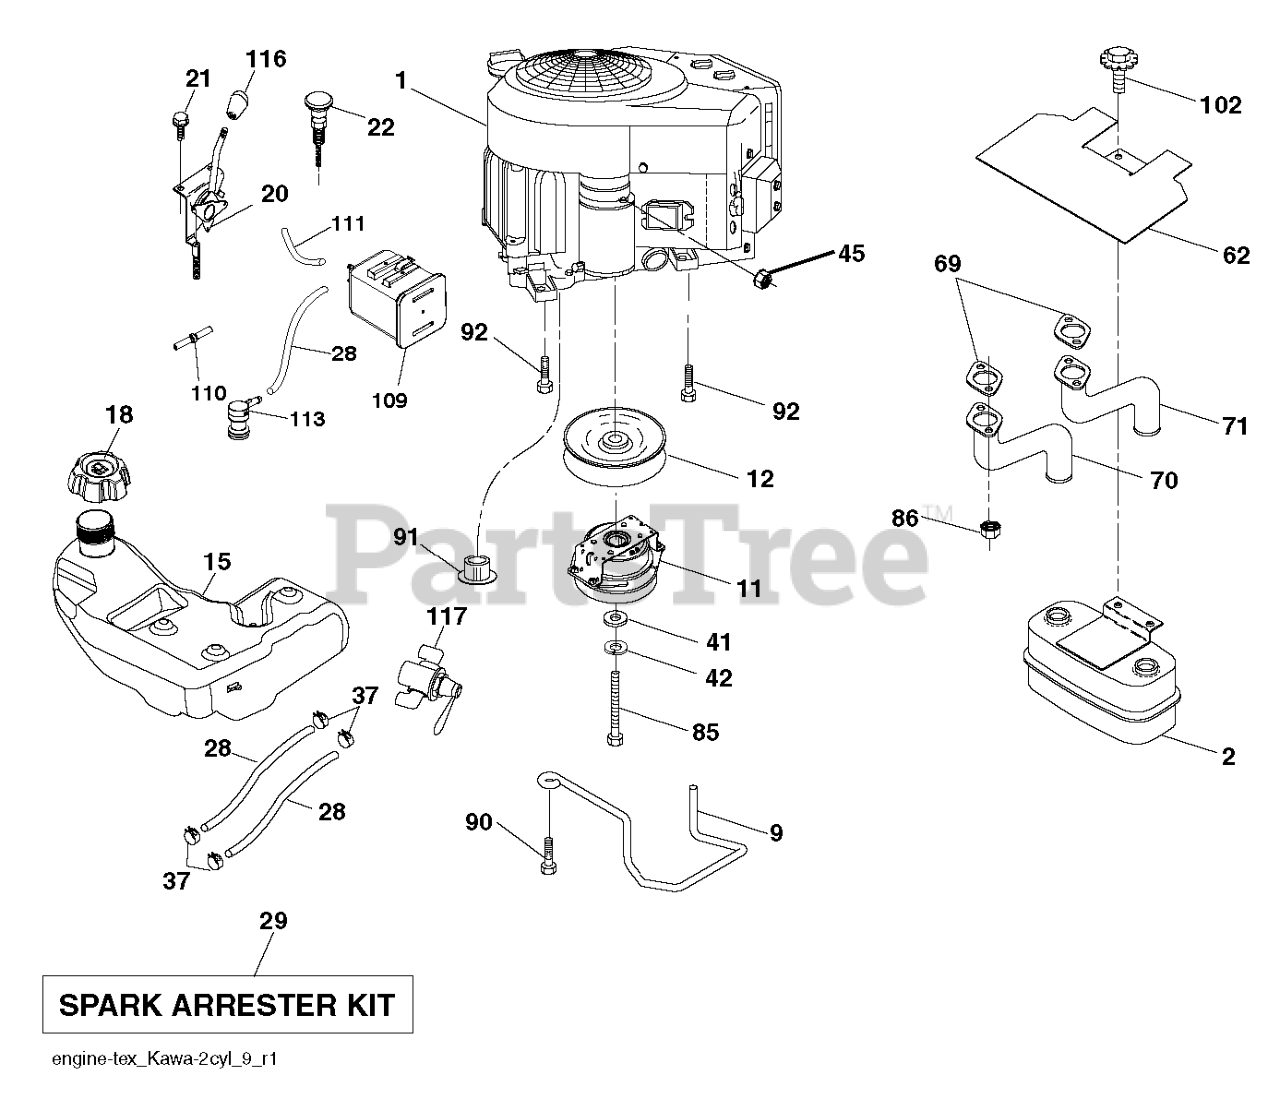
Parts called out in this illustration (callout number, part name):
2	MUFFLER.ASM.TWN.EXTNDED.DFLCTR
9	KEEPER BELT ENGINE
11	CLUTCH MZ ZTR GT.48/54"1.125"
12	PULLEY ENGINE
15	RP_TANK.ASM.4.GAL.CARB.2.PORT
18	CAP.FL.R.3'N/CARB.H.CROWN.498
20	CONTROL.THROTTLE.PRO.
21	SCREW.#10 X 0.750.BOS
22	CONTROL, CHOKE
28	LINE.FUEL.64"REAR.EMIS
29	KIT.SPARK ARRESTOR 794945 B&S
37	HOSE CLAMP
42	LOCKWASHER
45	NUT
62	SHIELD.HEAT.MUFFLER
70	TUBE.EXHAUST.LH.FR961/FR730
71	TUBE.EXHAUST.RH.FR961/FR730
85	BOLT HEX 7/16-20 X 3.75 GR. 5
86	BOLT.5/16-18UNCX3/4 W/SEMS.BLK
87	BOLT.5/16-18UNCX3/4 W/SEMS.BLK
90	SCREW 3/8-16X1
91	BUSHING.1.375OD
92	SCREW 3/8-16X1
109	CANNISTER, CARBON
110	VALVE.ASM.ANTI-SLOSH
111	RP PURGE LINE
113	VALVE.SLANT.CARTRDG.90 DEG.TEX
116	KNOB - SHIFT
117	VALVE FUEL RESERVE
